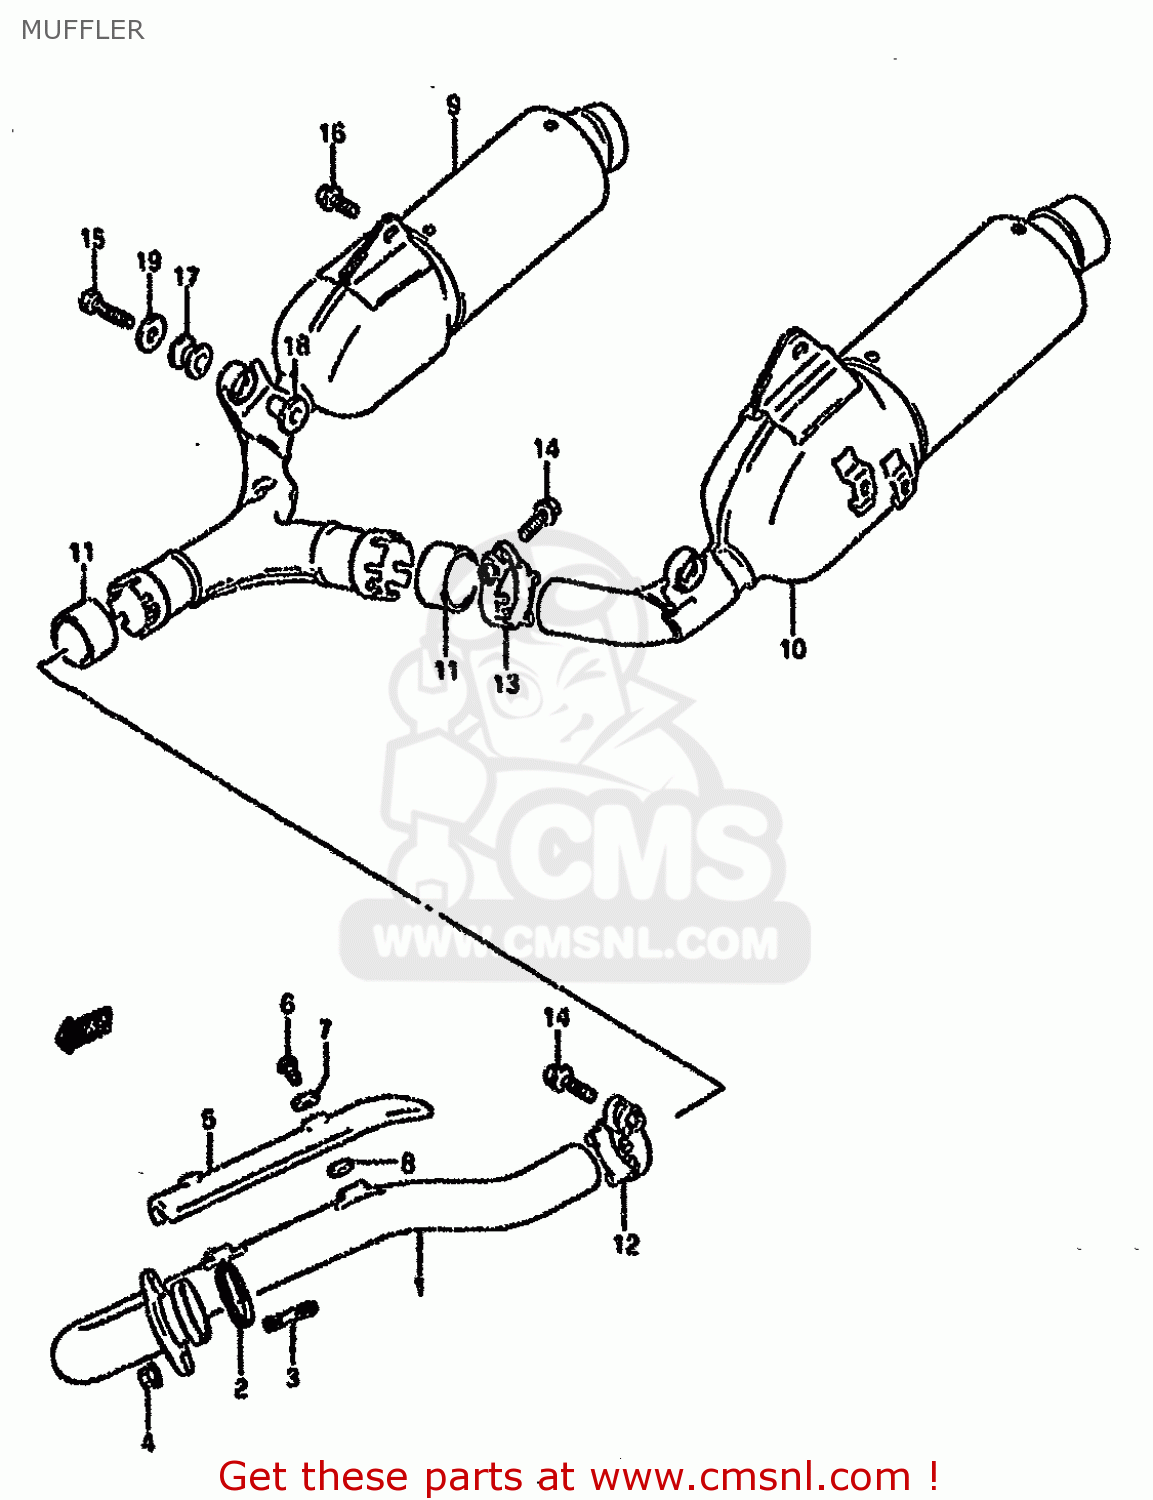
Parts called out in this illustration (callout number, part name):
1	PIPE,EXHAUST
2	GASKET,EXHAUST PIPE (NAS)
3	BOLT,STUD(8X20)
4	NUT
5	COVER,EXHAUST PIPE
6	SCREW(6X10)
7	WASHER(6.5X18X1)
8	GASKET(6X16X1.4) (NAS)
9	MUFFLER,R
10	MUFFLER ASSY,LH
11	CONNECTOR,MUFFLER
12	CLAMP,MUFFLER CONNECTOR
13	CLAMP,MUFFLER CONNECTOR
14	BOLT
15	BOLT(8X40)
16	BOLT(8X20)
17	CUSHION
18	SPACER(8.6X12X17.5)
19	WASHER (8.5X19X2.3)
